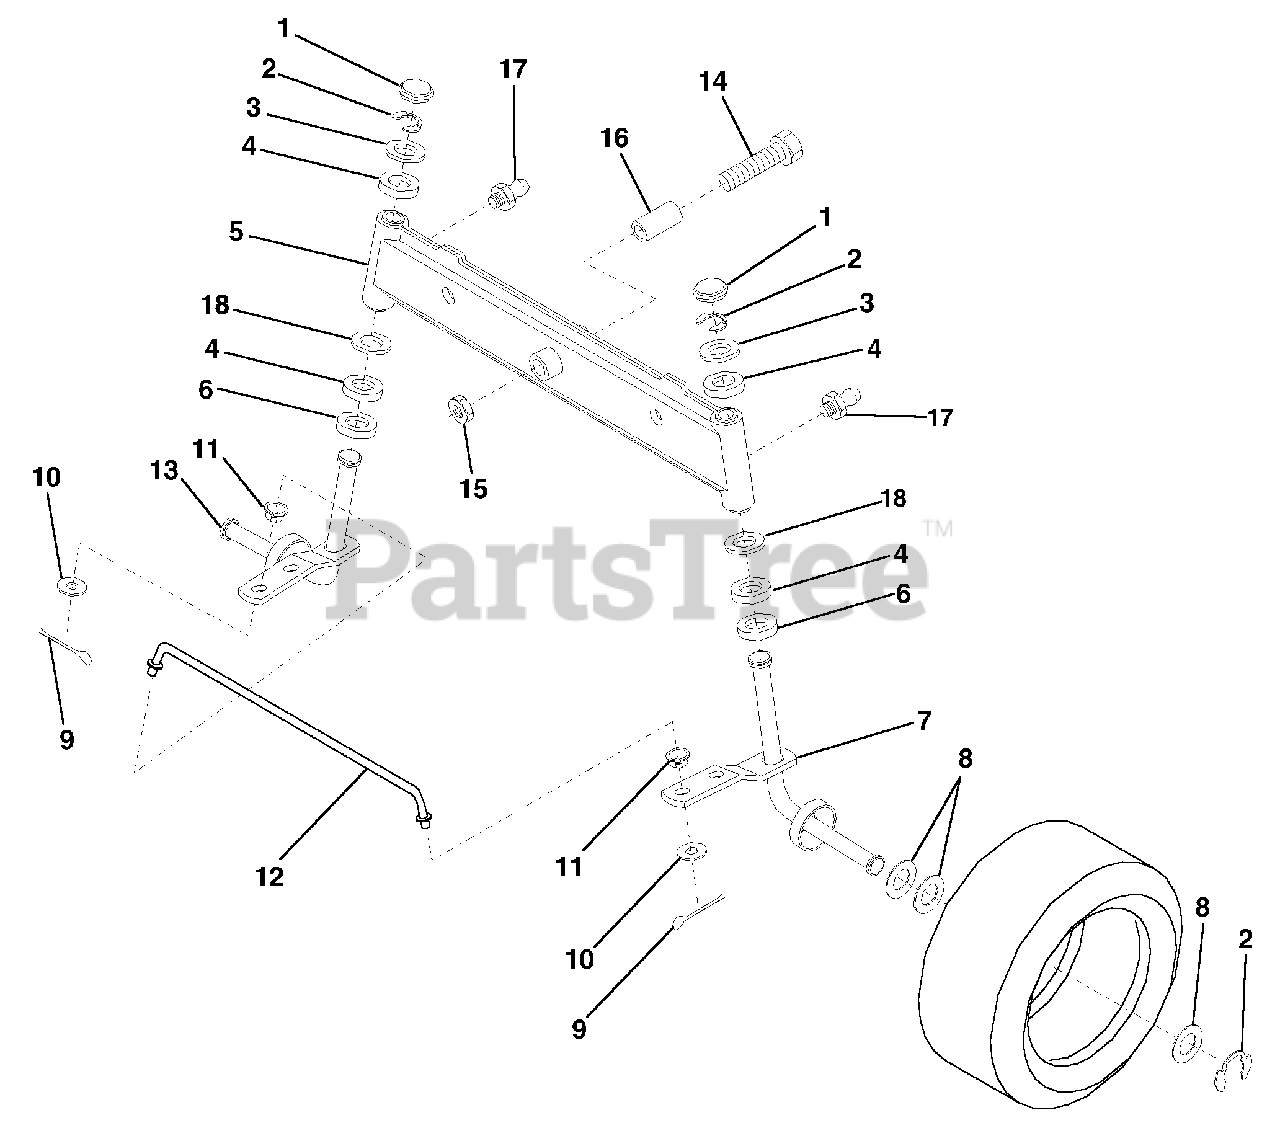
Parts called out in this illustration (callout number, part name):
1	Cap, Spindle
2	Ring, Clip
3	Washer 25/32 x 1-5/8 x 16 Ga.
4	Nyliner
5	Axle, Front
6	Bearing, Thrust
7	Spindle, R.H. Asm.
8	Washer 25/32 x 1-1/4 x 16 Ga.
9	Pin, Cotter 1/8 x 3/4
10	Washer 13/32 x 13/16 x 16 Ga.
12	Rod, Tie
13	Spindle, L.H. Asm.
14	Bolt Hex 5/1-11 x 3-1/2
15	Nut, Lock Flange 5/8-11
16	Spacer, Bearing Axle
17	Fitting, Grease
18	Washer 27/32 x 1-1/4 x 16 Ga.
